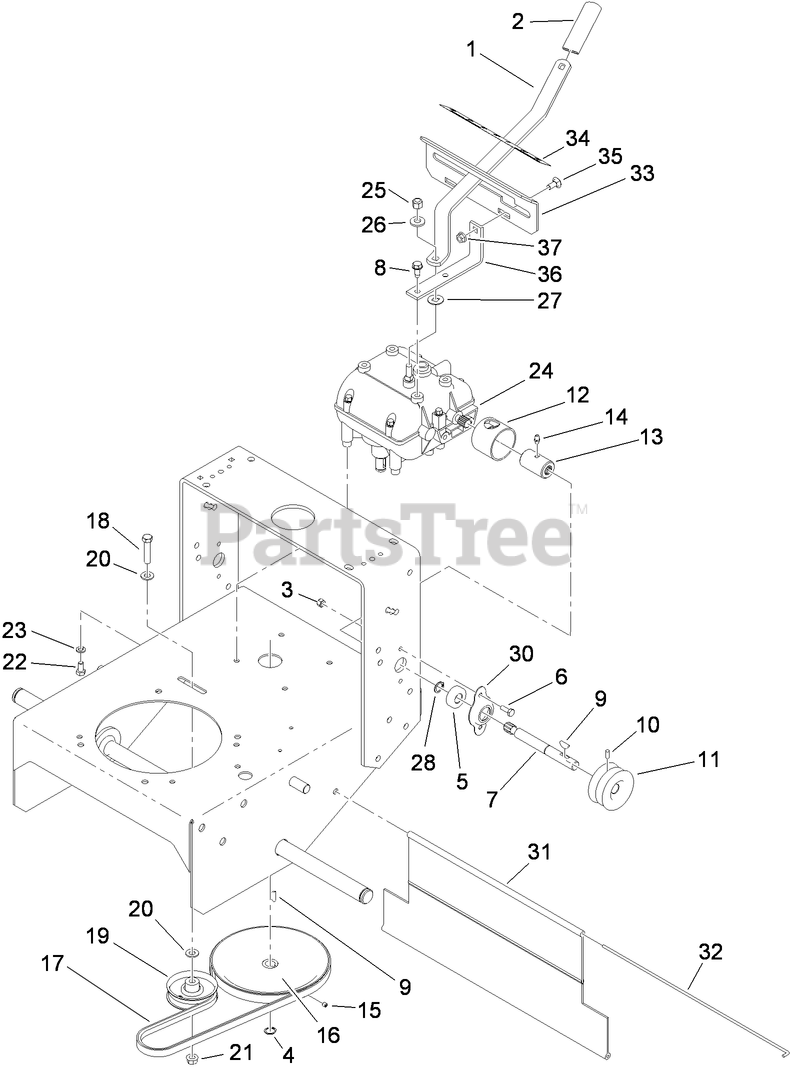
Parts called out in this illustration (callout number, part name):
1	LEVER-SHIFT
3	NUT-LOCK, NI
4	RING-SNAP, EXTERNAL
5	BEARING-SHAFT
6	SCREW-HH
7	SHAFT-OUTPUT
8	SCREW-HWH, THREAD CUT
9	KEY-WOODRUFF
10	SCREW-SET, HSH
11	PULLEY-TRANSMISSION
12	GUARD-COUPLER
13	COUPLER
14	FITTING-GREASE
15	SCREW-SET, HSH
16	PULLEY-DRIVEN
17	BELT V
18	SCREW-HH
19	PULLEY-IDLER
20	WASHER-FLAT
21	NUT-HF
22	SCREW-HH
23	WASHER-LOCK
24	TRANSMISSION
25	NUT-LOCK
26	WASHER-BELLEVILLE
27	WASHER
28	RING-RETAINING
30	FLANGE-OUTPUT
31	SHIELD-TRAILING
32	ROD-SHIELD
33	PLATE-SHIFT
34	DECAL-SPEED, GROUND
35	BOLT-CARR
36	BRACKET-PLATE, SHIFT
37	NUT-HF
